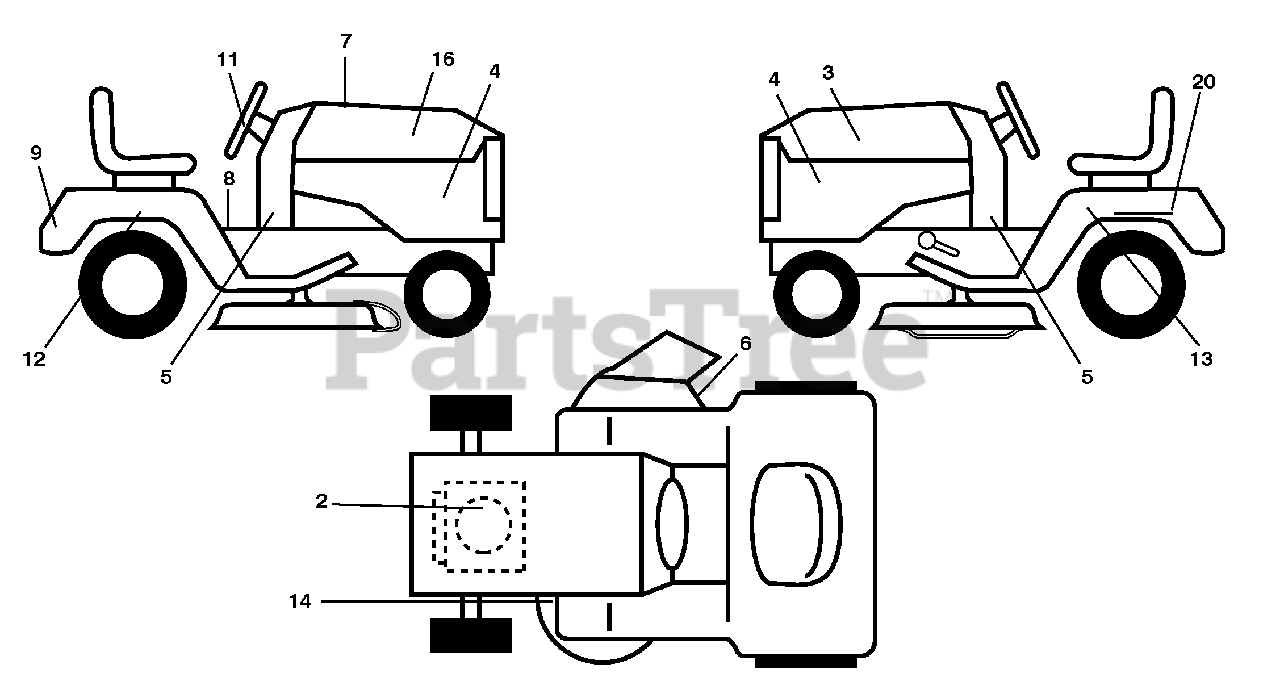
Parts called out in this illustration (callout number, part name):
2	Decal Eng. H.P.
3	Decal Hood LH
4	Decal Side Panel Logo
5	Decal Lwr Dash
6	Decal Warning, Keep Hand Away
7	Decal Replacement Parts
8	Decal Fender Warn S/F
9	Decal Fender Logo
11	Decal Ins Strg Whl
12	Decal Fend SD RH
13	Decal Fend SD LH
14	Decal V-Belt Schematic
16	Decal Hood RH
20	Decal Bat Dan/Psn
20	Pad Footrest LH
20	Pad Footrest RH
20	Manual Operator's (Eng/French)
20	Manual Parts (Eng/French)
